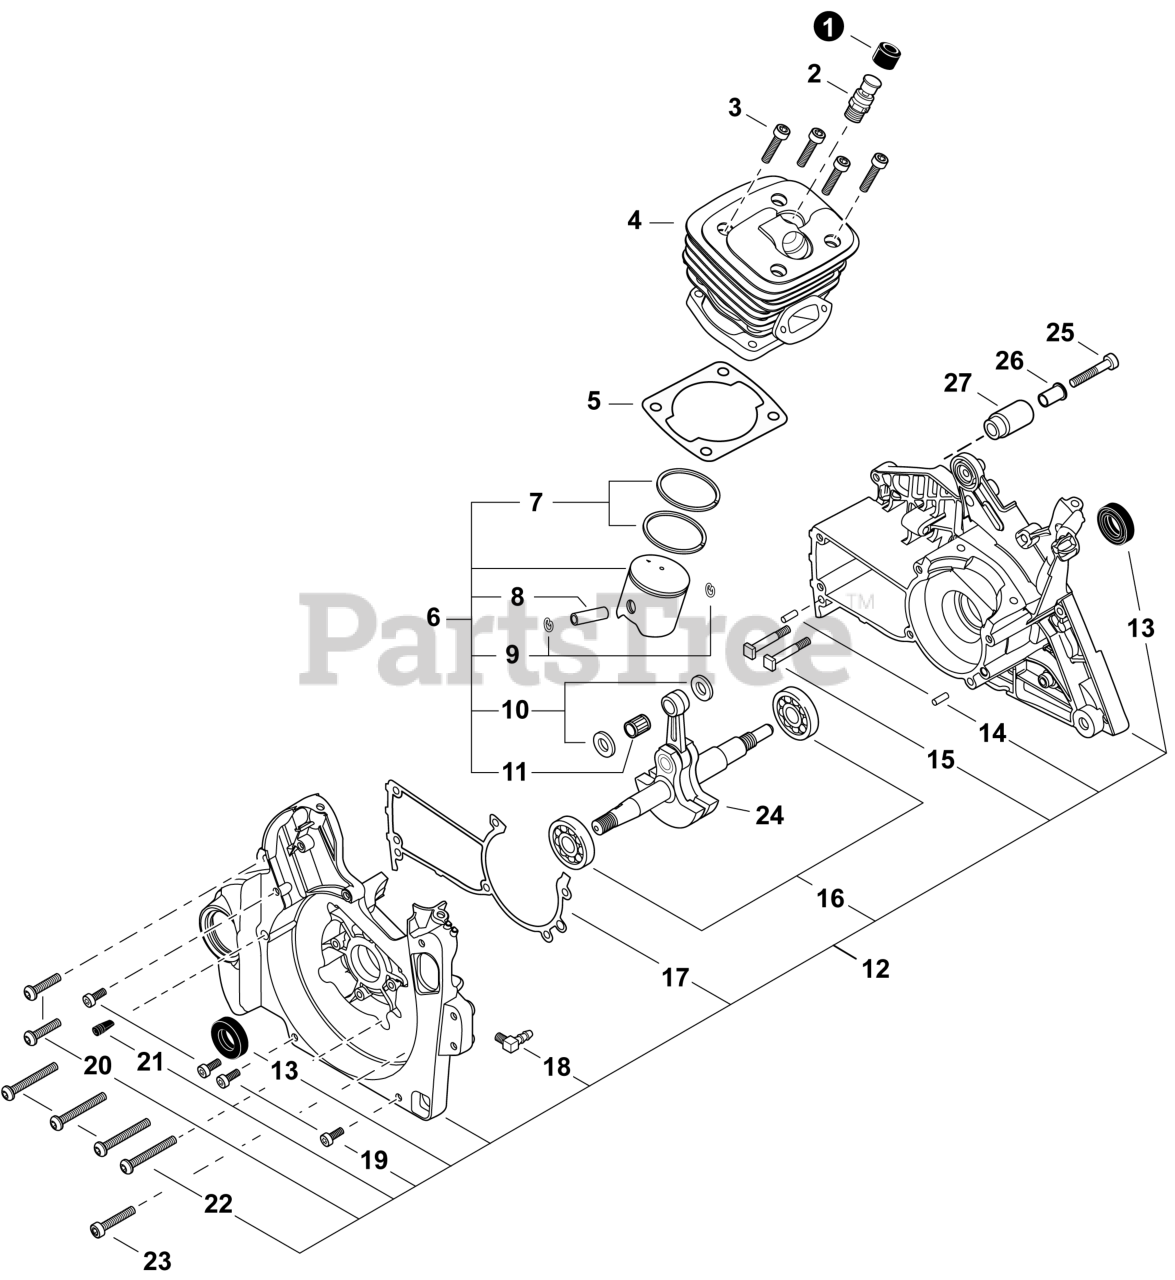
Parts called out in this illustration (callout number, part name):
1	COVER, DUST
2	VALVE ASSY, DECOMPRESSION
3	BOLT, TORX 5x25
4	CYLINDER
5	GASKET, CYLINDER
6	PISTON KIT
7	RING, PISTON
8	PIN, PISTON
9	RING, SNAP 11
10	WASHER, THRUST
11	BEARING, NEEDLE 11
12	CRANKCASE KIT
13	SEAL, OIL 15
14	PIN, LOCATING 5x10
15	STUD, GUIDE BAR 8
16	BEARING, BALL 6202
17	GASKET, CRANKCASE
18	CONNECTOR, PIPE
19	BOLT, TORX 5x20
20	BOLT, TORX 5x20
21	VENT ASSY
22	BOLT, TORX 5x35
23	BOLT, TORX 5x25
24	CRANKSHAFT ASSY
25	BOLT, TORX 5x35
26	COLLAR 5
27	CATCHER, CHAIN
